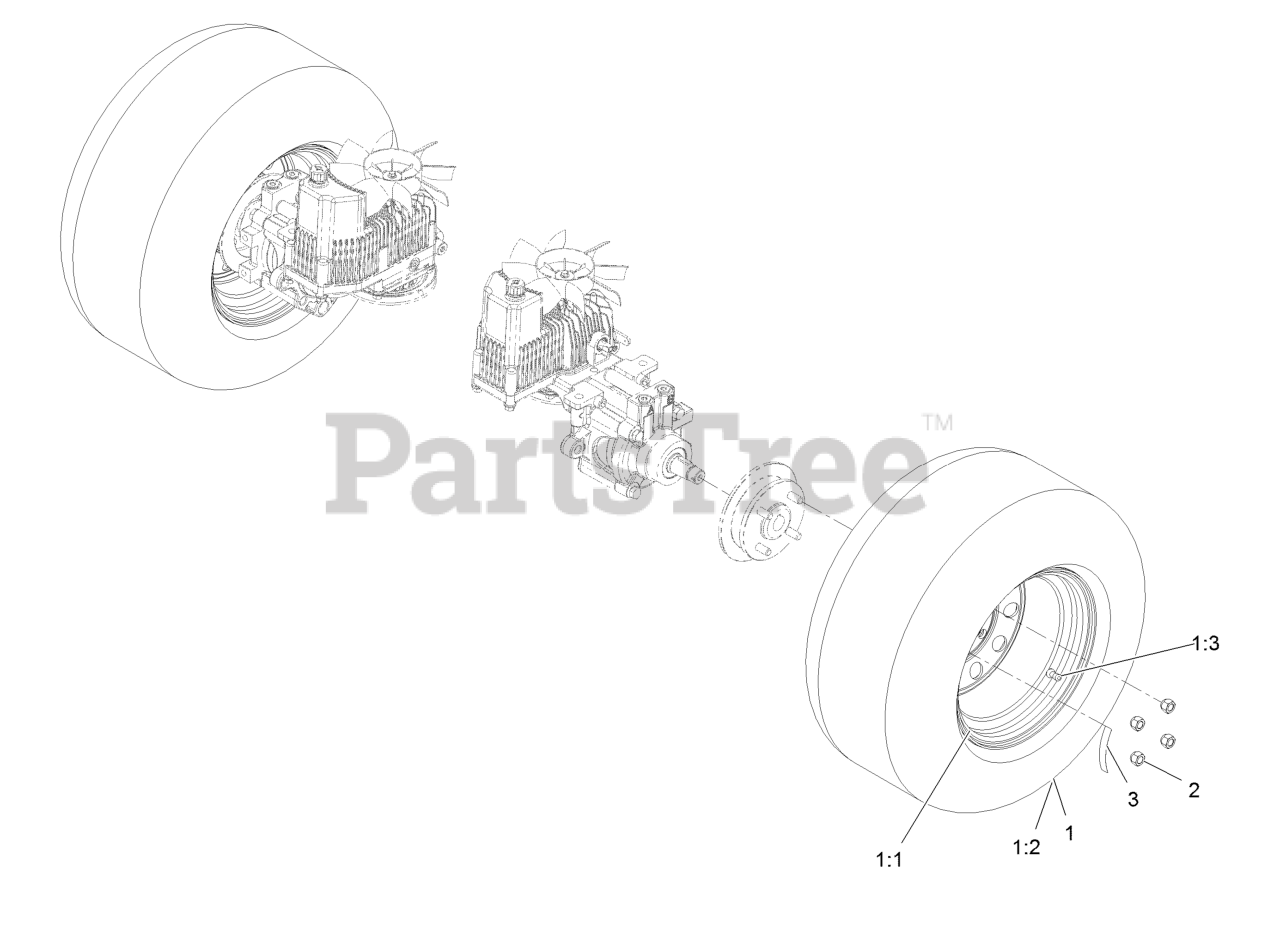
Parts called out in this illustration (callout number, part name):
1	Wheel And Tire ASM
1:3	Stem-Valve
2	Nut-Lug 1/2-20
3	Decal-Torque, Wheel Hub Lug
